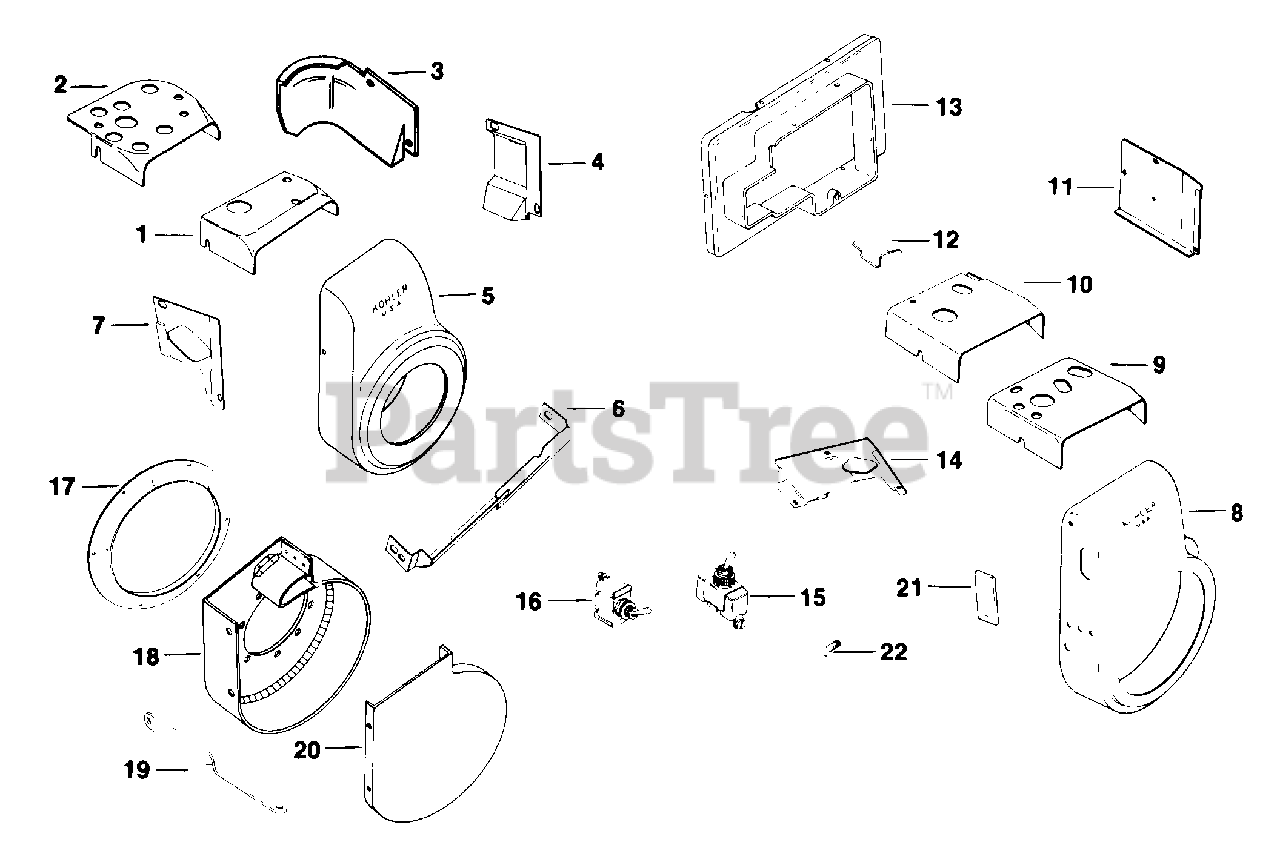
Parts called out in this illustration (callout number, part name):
2	BAFFLE, HEAD
2	BAFFLE - DISCONTINUED
3	BAFFLE, CYLINDER AIR
5	HOUSING - DISCONTINUED
7	BAFFLE, SIDE AIR
